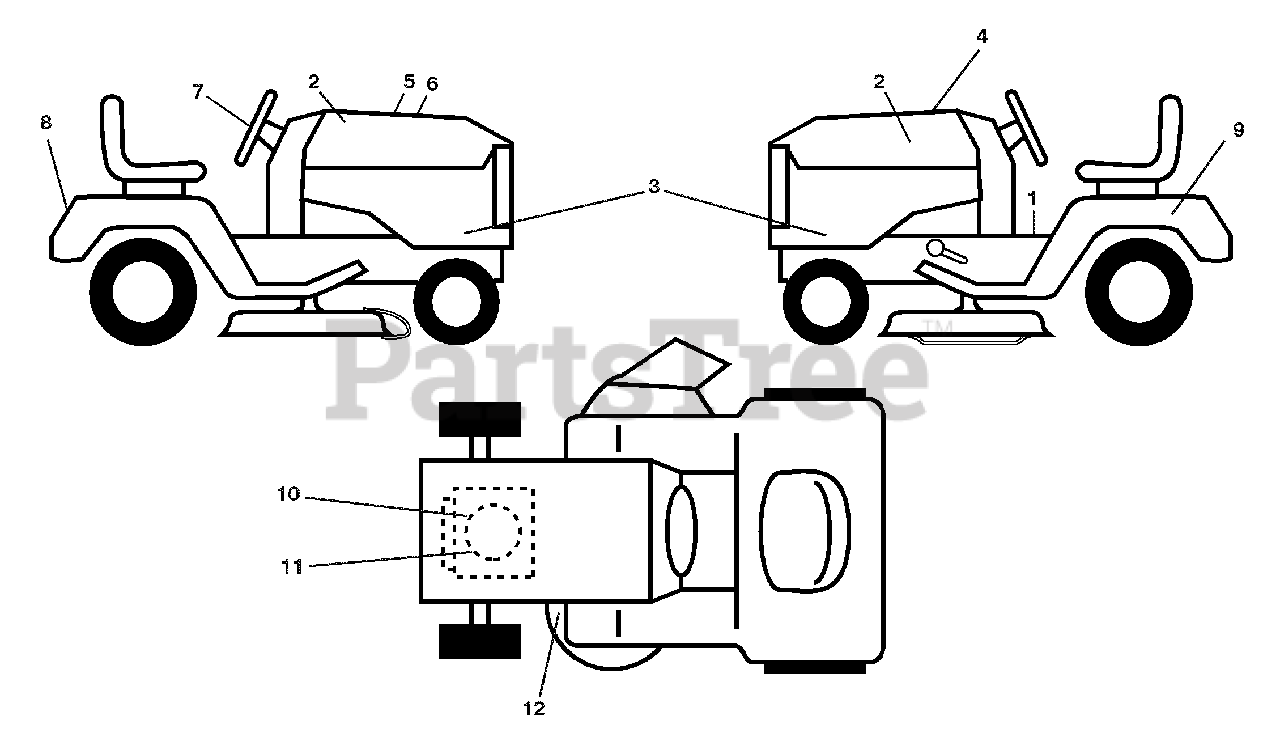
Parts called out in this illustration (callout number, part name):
1	Decal, Operators
2	Decal, Hood
3	Decal, Hood Panel SD
4	Decal, Hood Top Insert
5	Decal, Customer Respons.
6	Decal, Replacement
7	Decal, Steering Wheel
8	Decal, Fender
9	Decal, Battery Dnge/Poi
10	Decal, Engine HP
11	Decal, Engine
12	Decal, Mower V-Belt Schematic
12	Decal, Bypass
12	Pad, Footrest, LH
12	Pad, Footrest, RH
